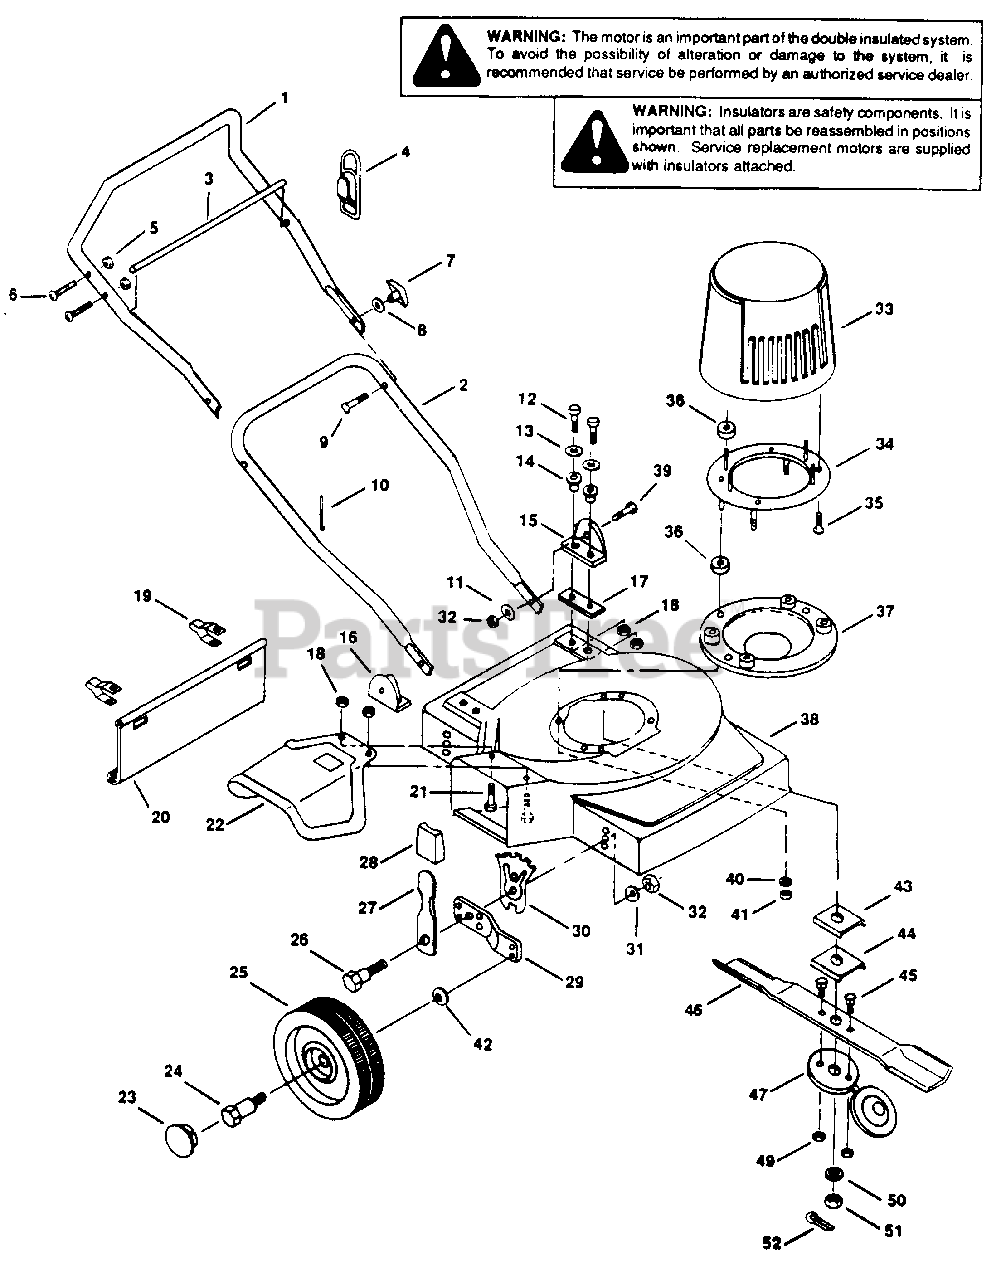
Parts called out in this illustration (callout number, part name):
1	Upper Handle
2	Lower Handle
3	Cord Control Rod
4	Cord Minder
5	Lock Nut #10-24
6	Mach. Screw #10-24 x 1-1/8"
7	Knob- Handle
8	Curved Washer 5/16" I.D.
9	Saddle Bolt 5/16-18 x 2
10	Plastic Tie
11	Flat Washer 3/8" I.D
12	Hex Bolt 1/4-20 x 7/8"
13	Flat Washer 1/4" I D.
14	Insulator - Handle Bracket
15	LH Handle Bracket
16	RH Hardle Bracket
17	Insulator Strip
18	Lock Nut 1/4-20 Thd.
19	Clip - Trail Shield
20	Trail Shield
21	Carriage Bolt 1/4-20 x 3/4"
22	Safety Chute Guard
23	Hub Cap
24	Wheel Bolt
25	Front Wheel - 6"
26	Pivot Bolt - Adjuster
27	Lever- Adjuster
28	Knob - Adjuster
30	Plate - Height Adjuster
31	Bell Washer
32	Hex Nut 3/8-16 Thd.
33	Motor Cover (Gray)
34	Plate Assembly
35	Tapping Screw #10 x 3/4
36	Spacer - Motor Mounting
37	Shield
38	Deck Ass'y. -16" Steel
39	Hex Bolt 3/8-16 x 3/4"
40	Flat Washer 5/16" I.D.
41	Lock Nut 5/16-18 Thd.
42	Bell Washer (Small)
43	Adapter - Blade Mounting
44	Insulator - Blade Adapter
45	Carriage Bolt 5/16-18 x 3/4
46	Blade -16" Electric
47	Insulator- Blade
49	Keps Nuts 5/16-18 Thd.
50	Washer
51	Slotted Nut 1/2-20 Thd.
52	Coner Pin (Stainless Steel)
